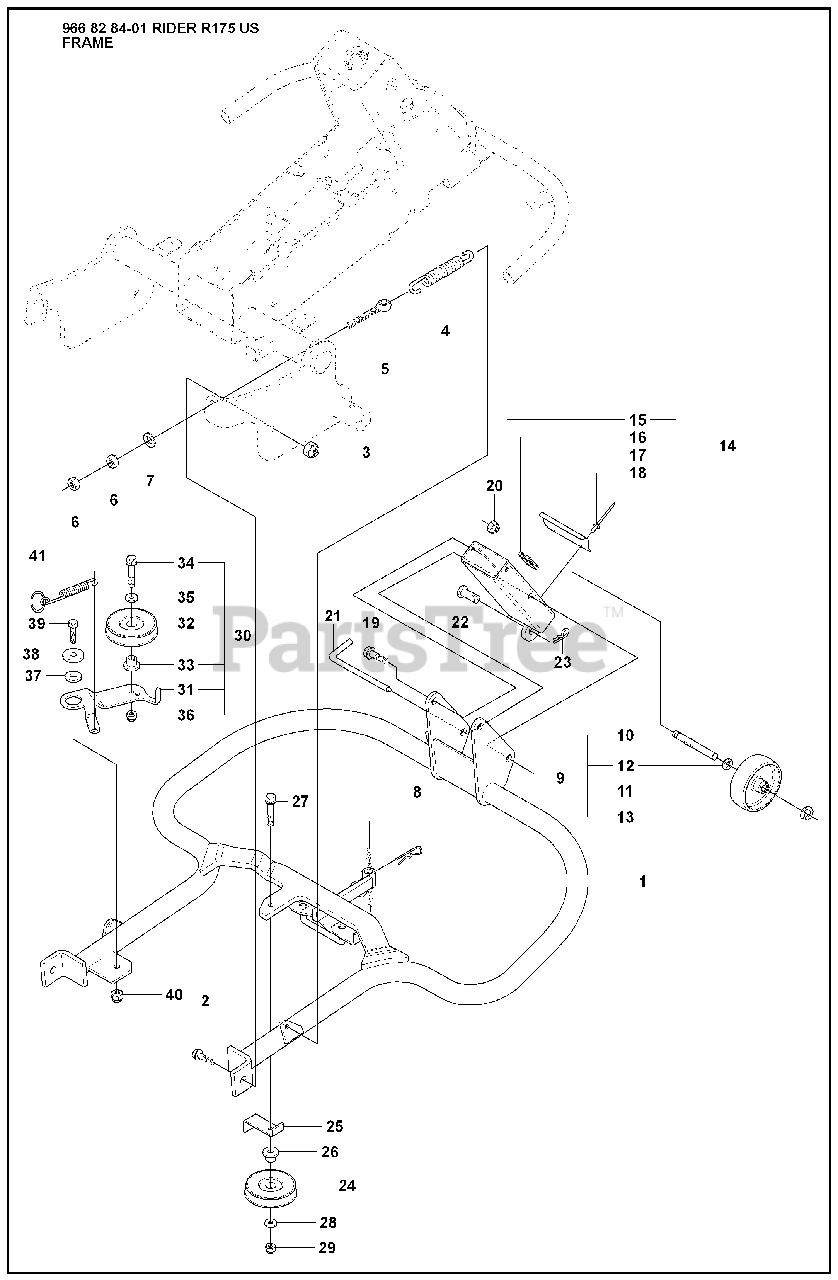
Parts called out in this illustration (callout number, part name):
3	Lock Nut, Fiber M12 DIN 985 Z/P
6	NUT
7	WASHER
9	WHEEL ASSY
13	RETAINING RING
20	LOCKNUT M8
29	LOCKNUT M8
30	BELT TENSIONER ASSY
36	LOCKNUT M8
40	NUT
